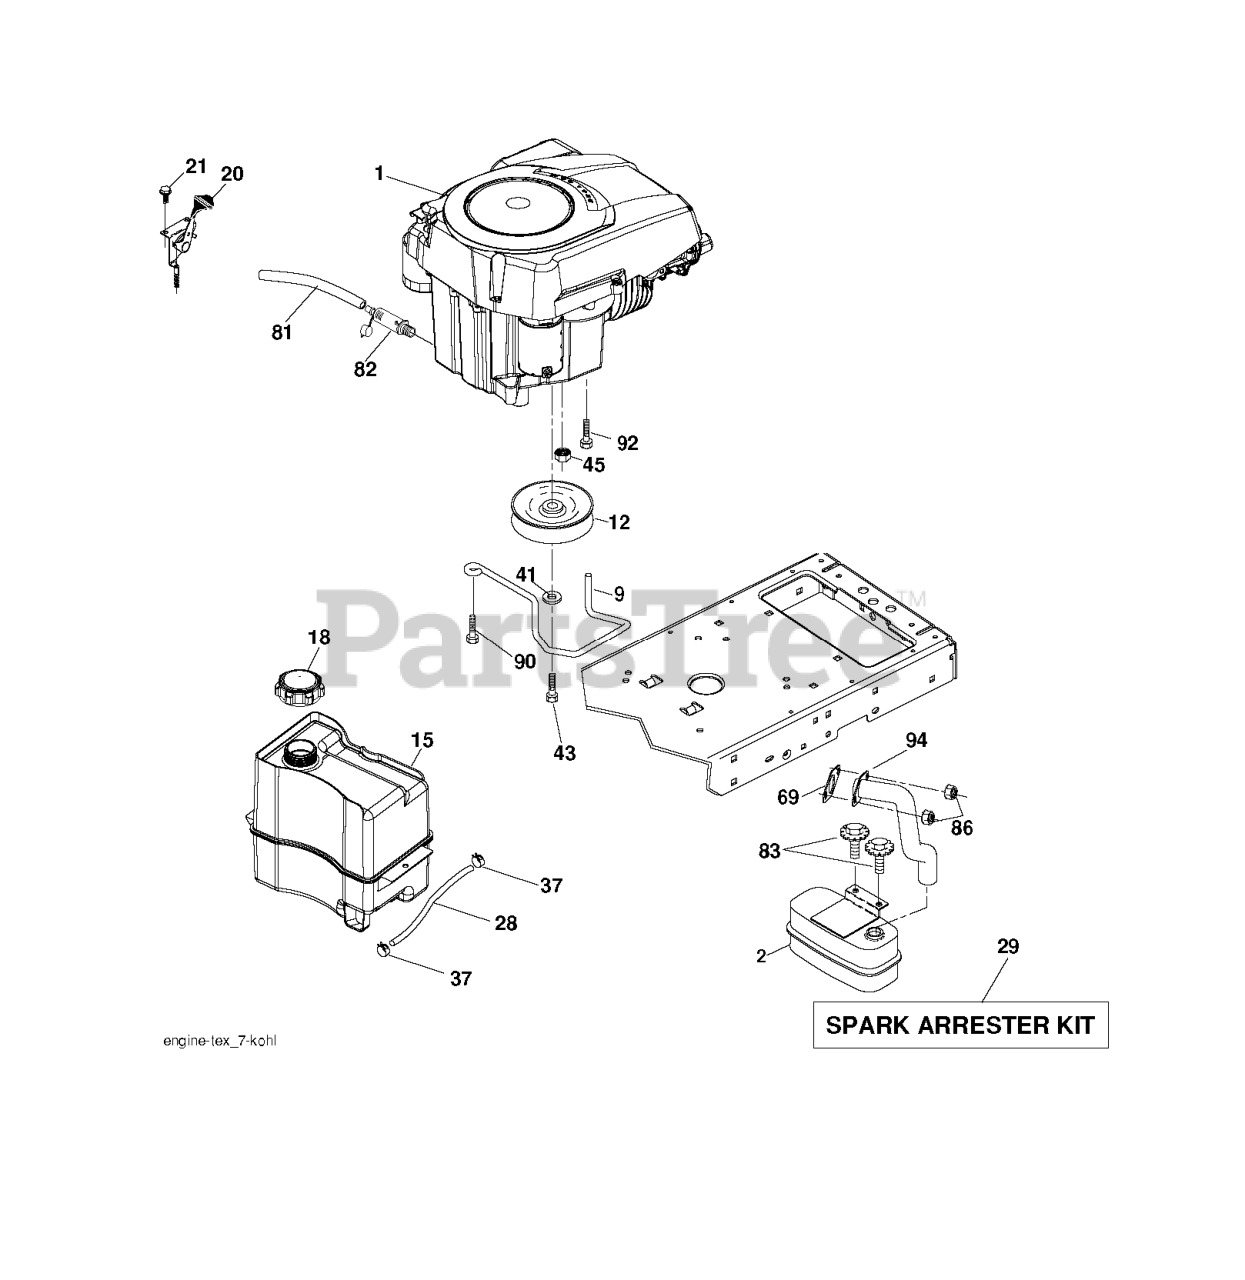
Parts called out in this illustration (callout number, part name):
2	MUFFLER.SINGLE.CYL.KOHL/B&S
9	KEEPER.BELT.ENGINE.3.25 (3 2)
12	PULLEY ENGINE
15	RP TANK FUEL FRT 1.5 GAL
18	FUEL CAP
20	CONTROL.TH/CK.COBRA.KO
21	SCREW
28	LINE.FUEL.20
29	KIT.SPARK ARRESTOR 794945 B&S
37	HOSE CLAMP
41	LOCKWASHER
43	BOLT HEX 7/16-20X4-1/4"
45	NUT
81	Tube Drain Oil Easy
82	Plug Drain Oil
83	BOLT.5/16-18UNCX3/4 W/SEMS.BLK
86	NUT.HEX.FLANGE.TOPLOCK
90	SCREW 3/8-16X1
92	SCREW 3/8-16X1
94	RP.TUBE.EXHAUST.KOHL.COURAGE
